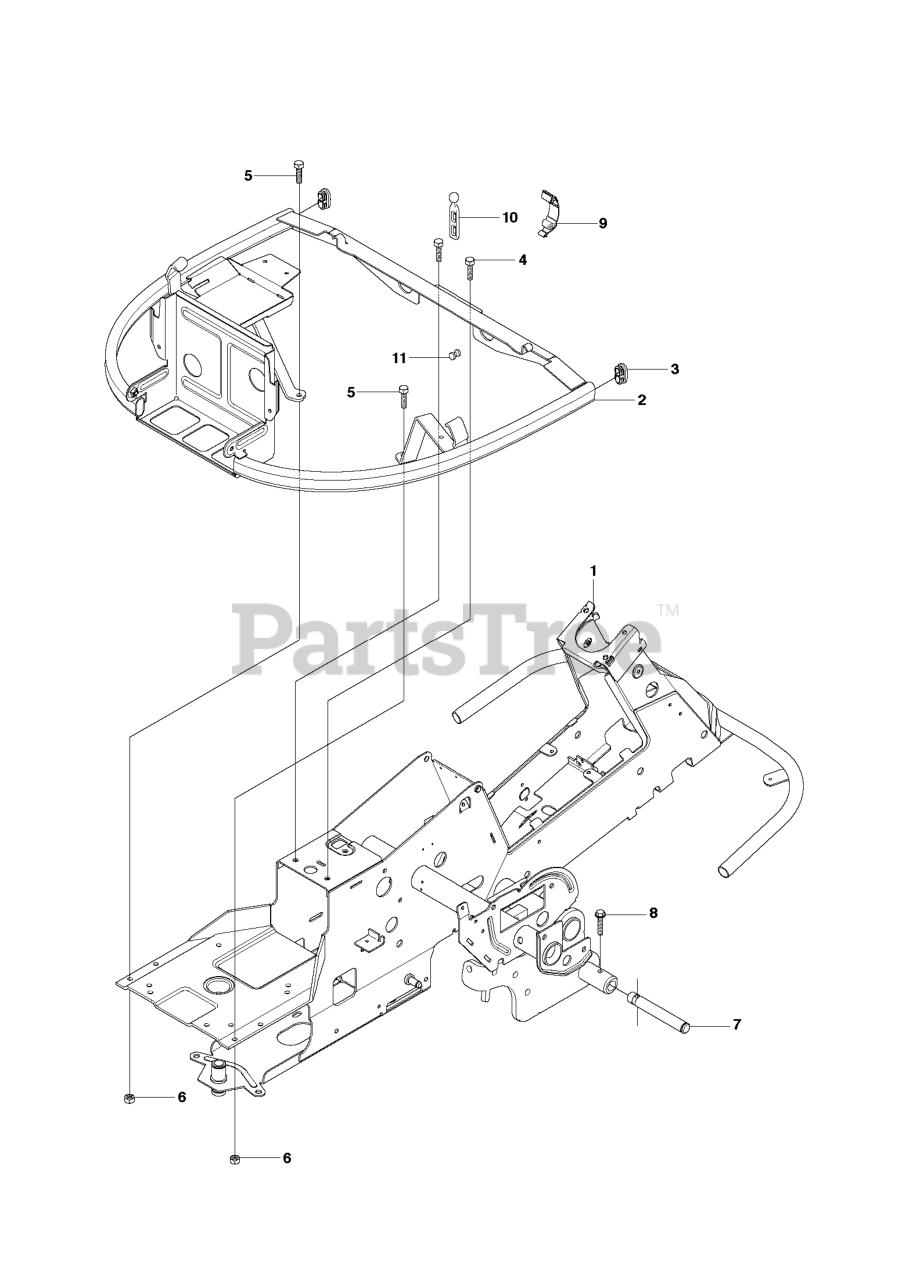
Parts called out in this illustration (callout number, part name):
6	LOCKNUT M8
8	BOLT FLANGE - M8X40\
9	CLIP GRAY
11	Support Strap
